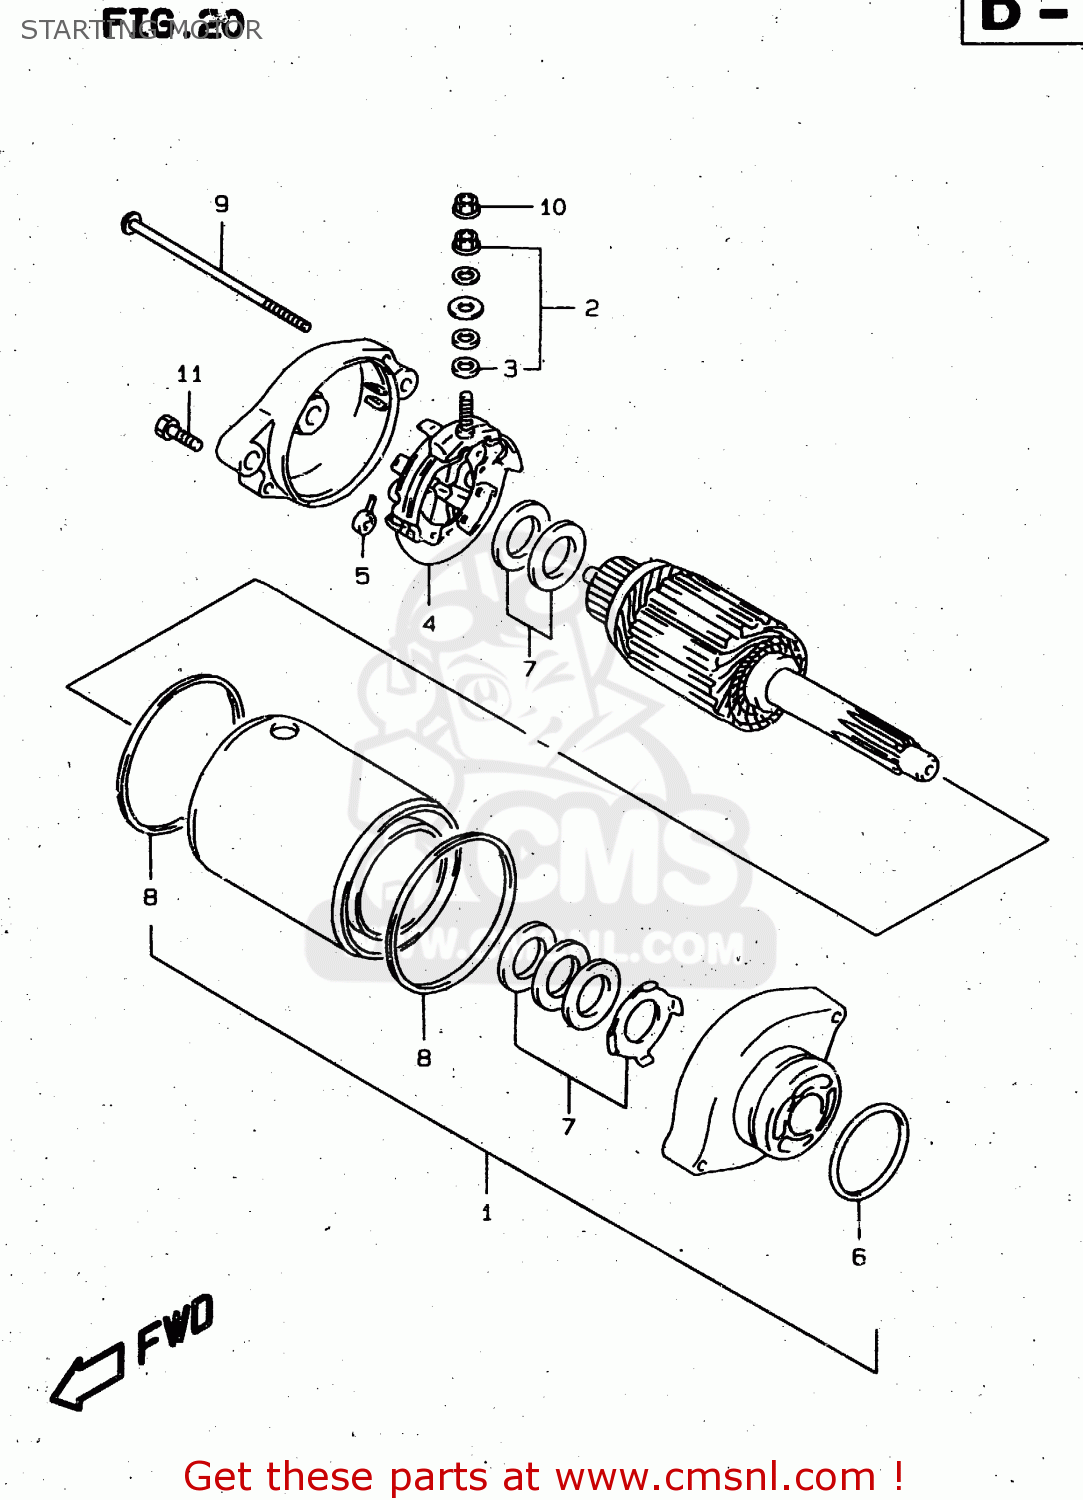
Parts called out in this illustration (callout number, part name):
1	MOTOR ASSY,STARTING
2	TERMINAL SET,BRUSH
3	O RING
4	HOLDER SET,BRUSH
5	SPRING,BRUSH
6	O RING
7	WASHER SET
8	SQUARE RING
9	BOLT
10	NUT
11	BOLT,G/S SWITC
